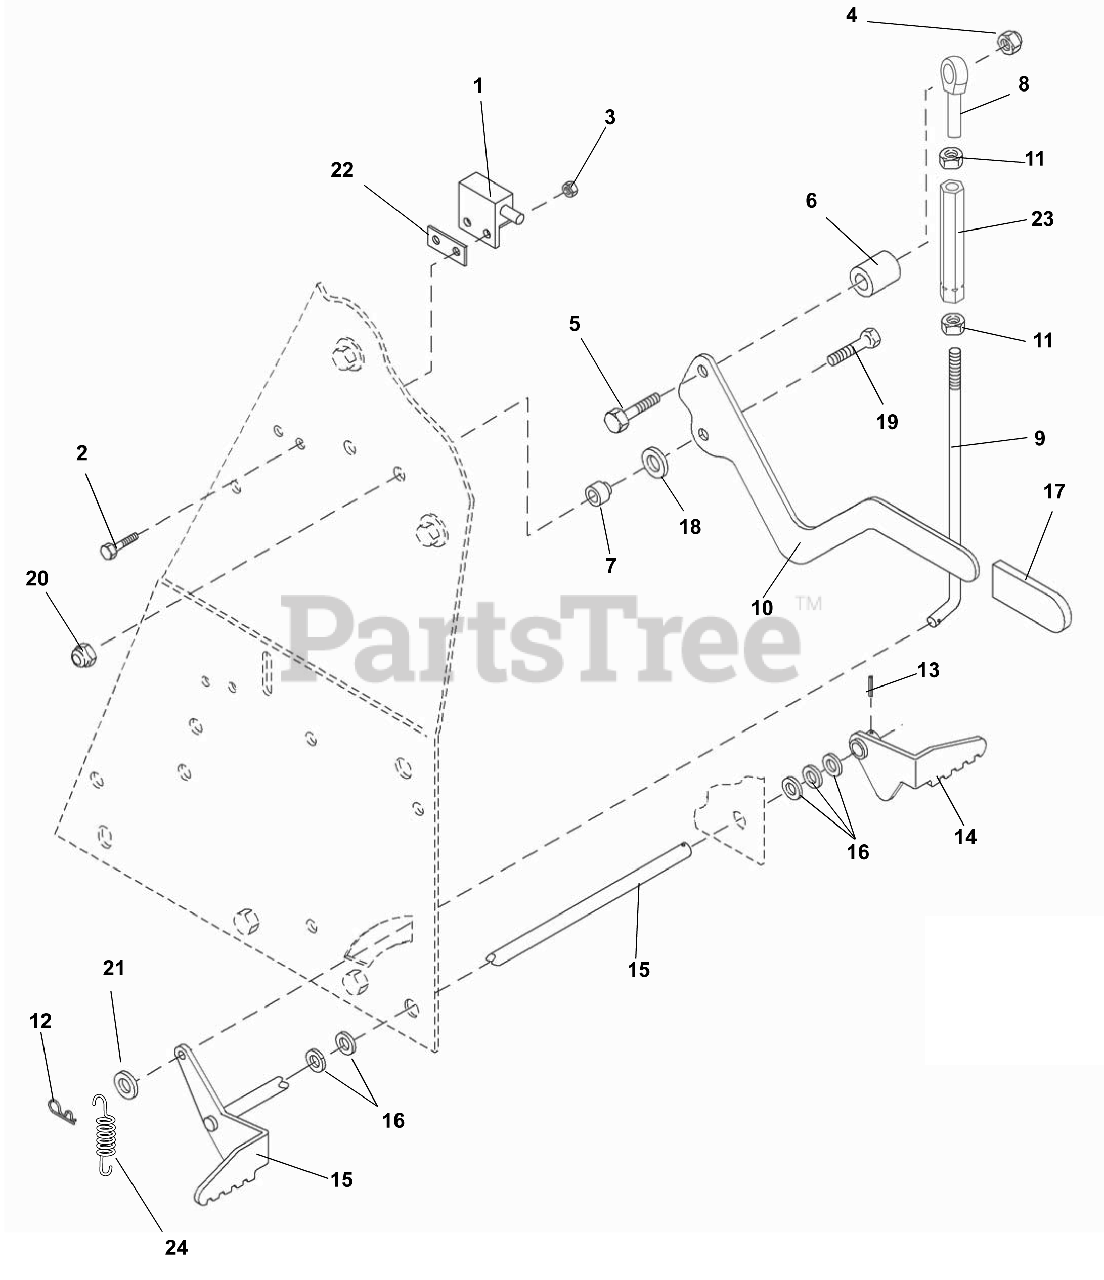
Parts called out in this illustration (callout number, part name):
1	SWITCH
2	CAP SCREW, M5 X 0.8 X 20
3	NUT-HEX M5X.8 PL
4	@NUT-LK-CTR .38-16 YWZC
5	@BLT-HEX .38-16X2.00 GR5 YWZC
7	BUSHING
8	END, LH TIE ROD
9	ROD
11	@NUT-HEX .38-16 YWZC
12	PIN, HAR .094X1.53 5/16-1/2 Y
13	PIN, SPRING
14	WMT, RH BRAKE ARM
15	WMT, LH BRAKE SHAFT
16	WASHER,JDS24-.891X1.375X.048-S
17	GRIP
18	WASHER, 17/32" X 15/16" X 0.06
19	BLT M10 X 1.5X40 YWZC
20	NUT-LK-NYL M10-1.5 YWZC
21	@WSHR-FL-STL.406X.812X.065 YWZ
22	SPACER PLATE
23	TURN BUCKLE
24	SG-TENS .056X.60X4.40
